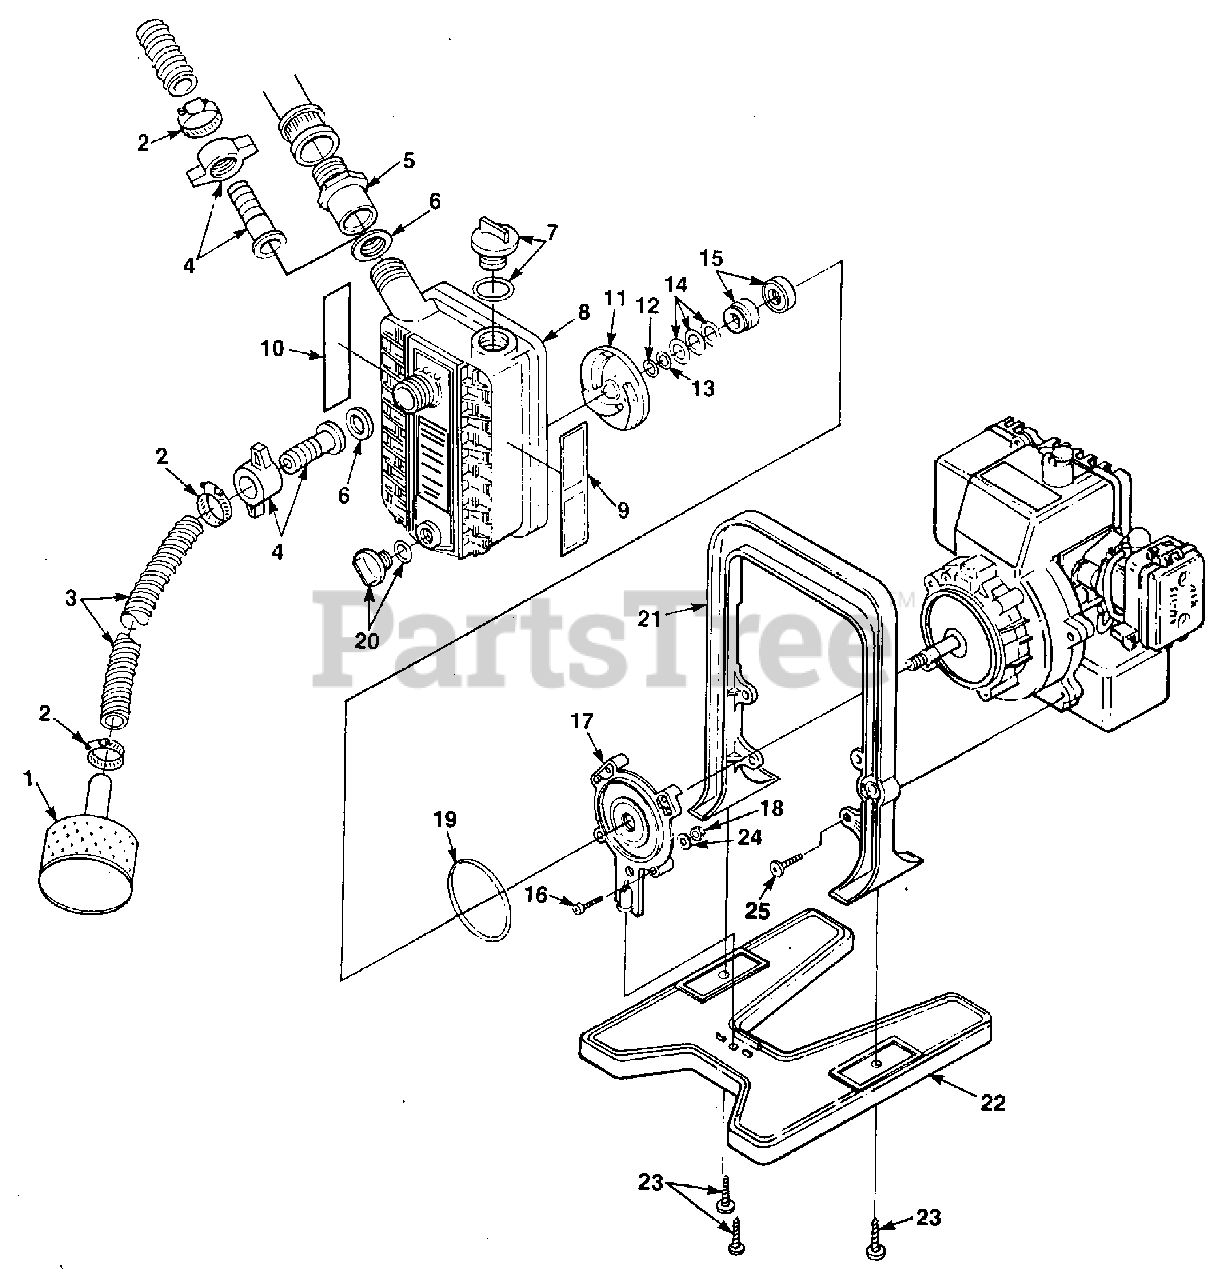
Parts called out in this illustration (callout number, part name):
1	STRAINER (1")
3	HOSE (1")
4	BARBED COUPLING
5	ADAPTOR- Garden Hose
7	CAP w/O-RlNG
8	PUMP BODY & DECALS
9	DECAL- Operation
10	DECAL- Warning
11	IMPELLER
12	SHIM- (.030") (Impeller)
13	SHIM- (.015") (Impeller)
14	SHIM- (.030") (Seal)
16	SCREW- (10-24 x 1")
17	ADAPTER- (Engine to Pump)
18	NUT (m5)
19	O-RING
20	CAP- w/O-Ring
21	HANDLE- Engine mtg.
22	BASE PLATE
23	SCREW- (10-14 x 3/4")
24	WASHER- Flat
25	SCREW- (10-24 x 1")
